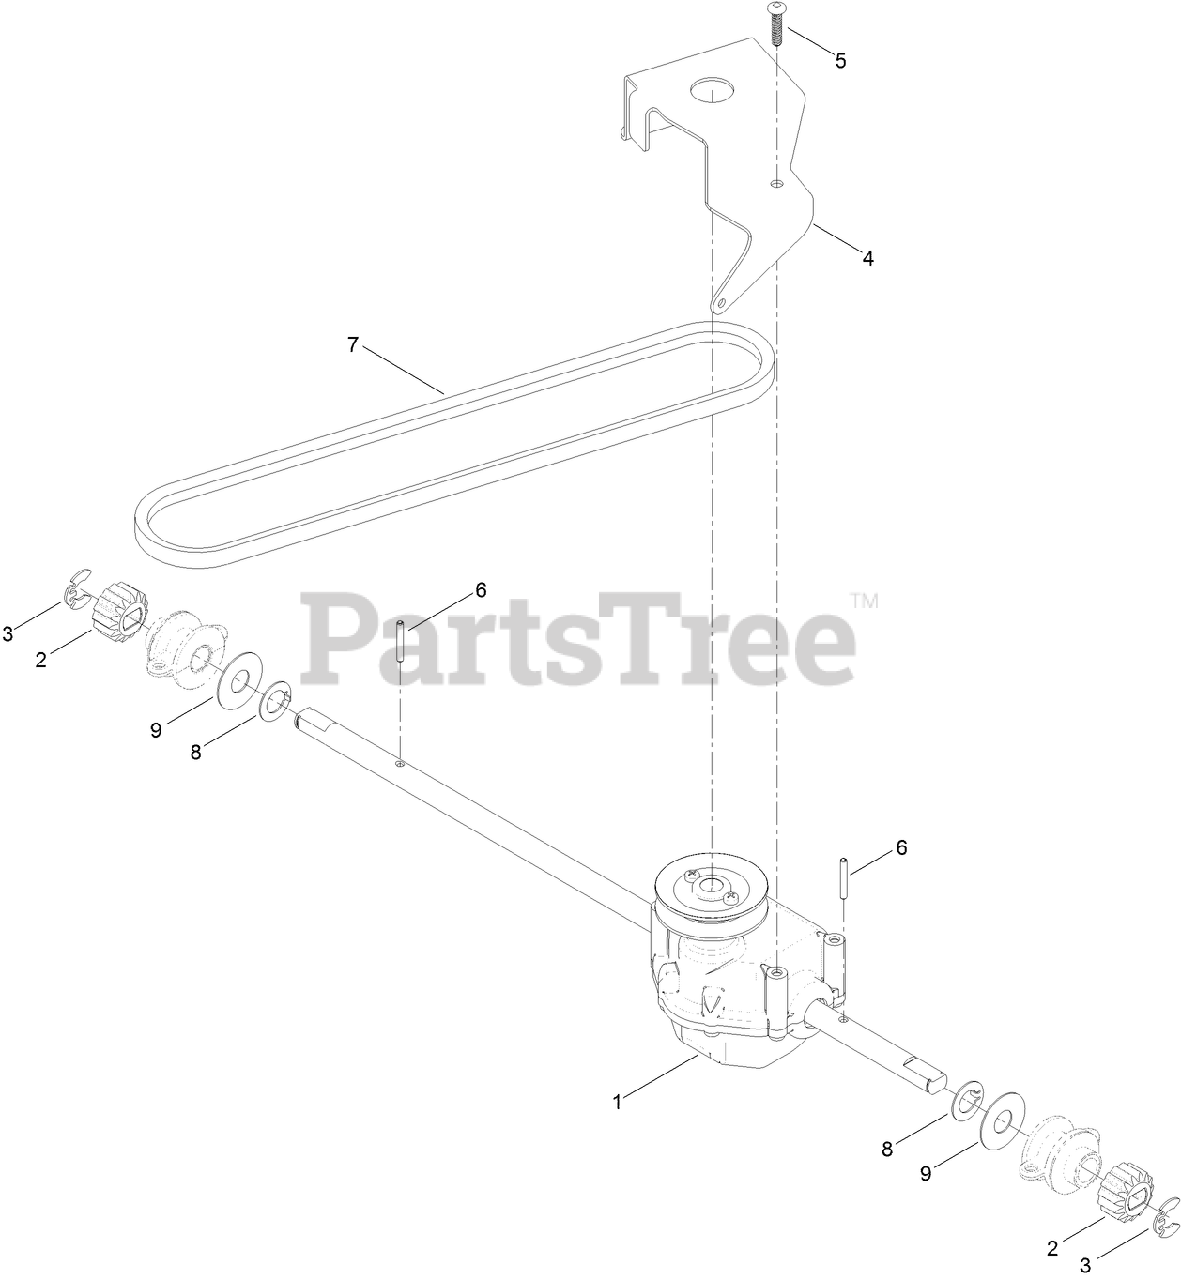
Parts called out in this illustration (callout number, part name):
1	TRANSMISSION-GEARBOX
2	GEAR-PINION, 15T
3	RING-RETAINING,CLIP
4	BRACKET-TRANSMISSION
5	SCREW-PLASTITE
6	PIN-ROLL
7	V-BELT
8	WASHER-THRUST, KEYED
9	WASHER-PLAIN
